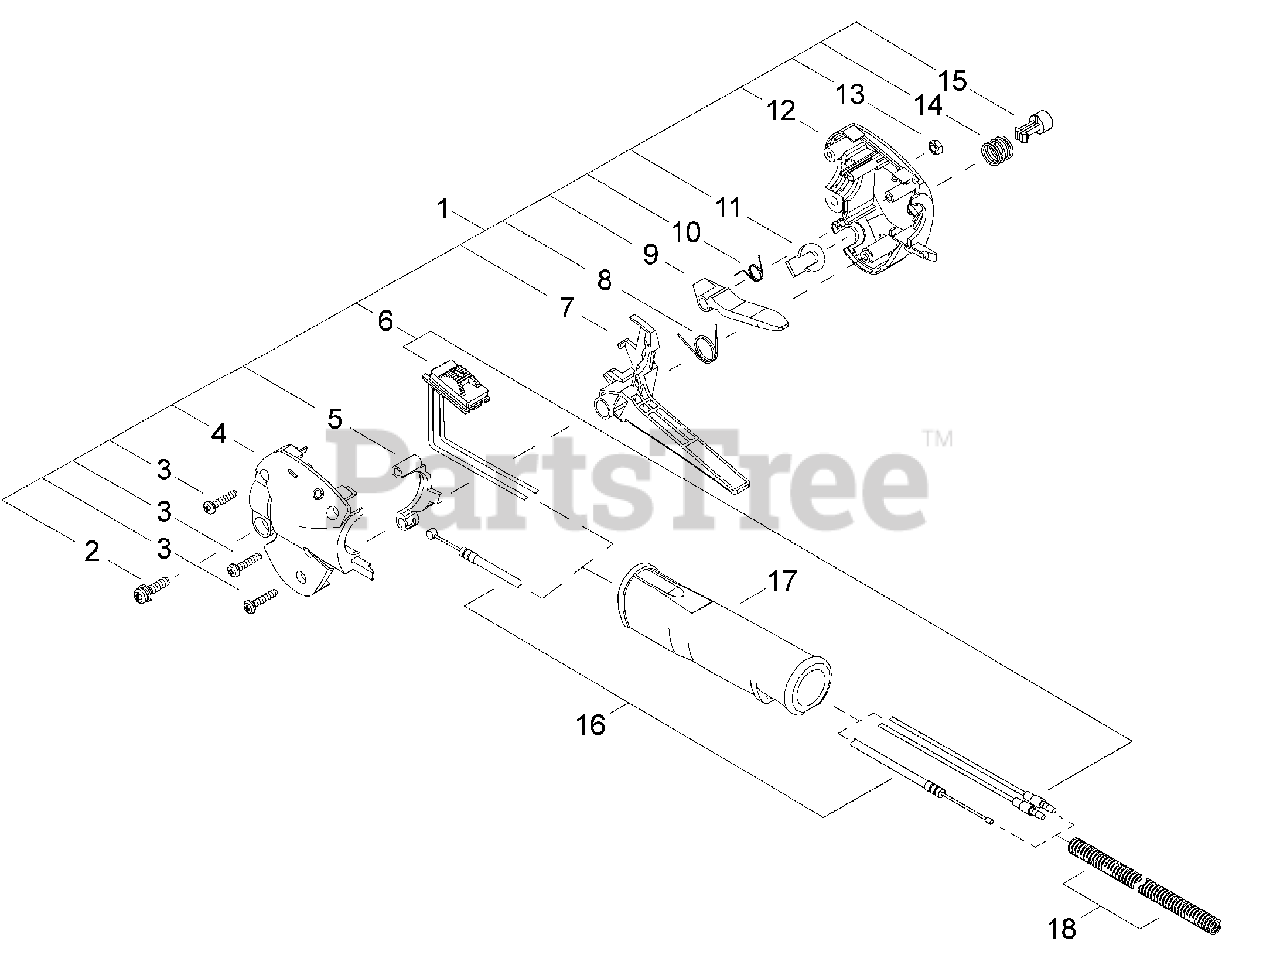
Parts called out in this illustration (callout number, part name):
1	THROTTLE CONTROL ASSY
2	SCREW M5×20
3	SCREW, TAPPING M4×20
4	CONTROL HANDLE - LEFT
5	LOCKOUT, THROTTLE
6	SWITCH, ON-OFF
7	TRIGGER, THROTTLE
8	SPRING, THROTTLE RETURN
9	LEVER, THROTTLE LOCKOUT
10	SPRING, THROTTLE LOCKOUT
11	PLUG
12	CONTROL HANDLE - RIGHT
13	NUT M5
14	SPRING, COMPRESSION
15	BUTTON, THROTTLE LOCK
16	CABLE, THROTTLE
17	GRIP, REAR
18	TUBE, PLASTIC PROTECTIVE
